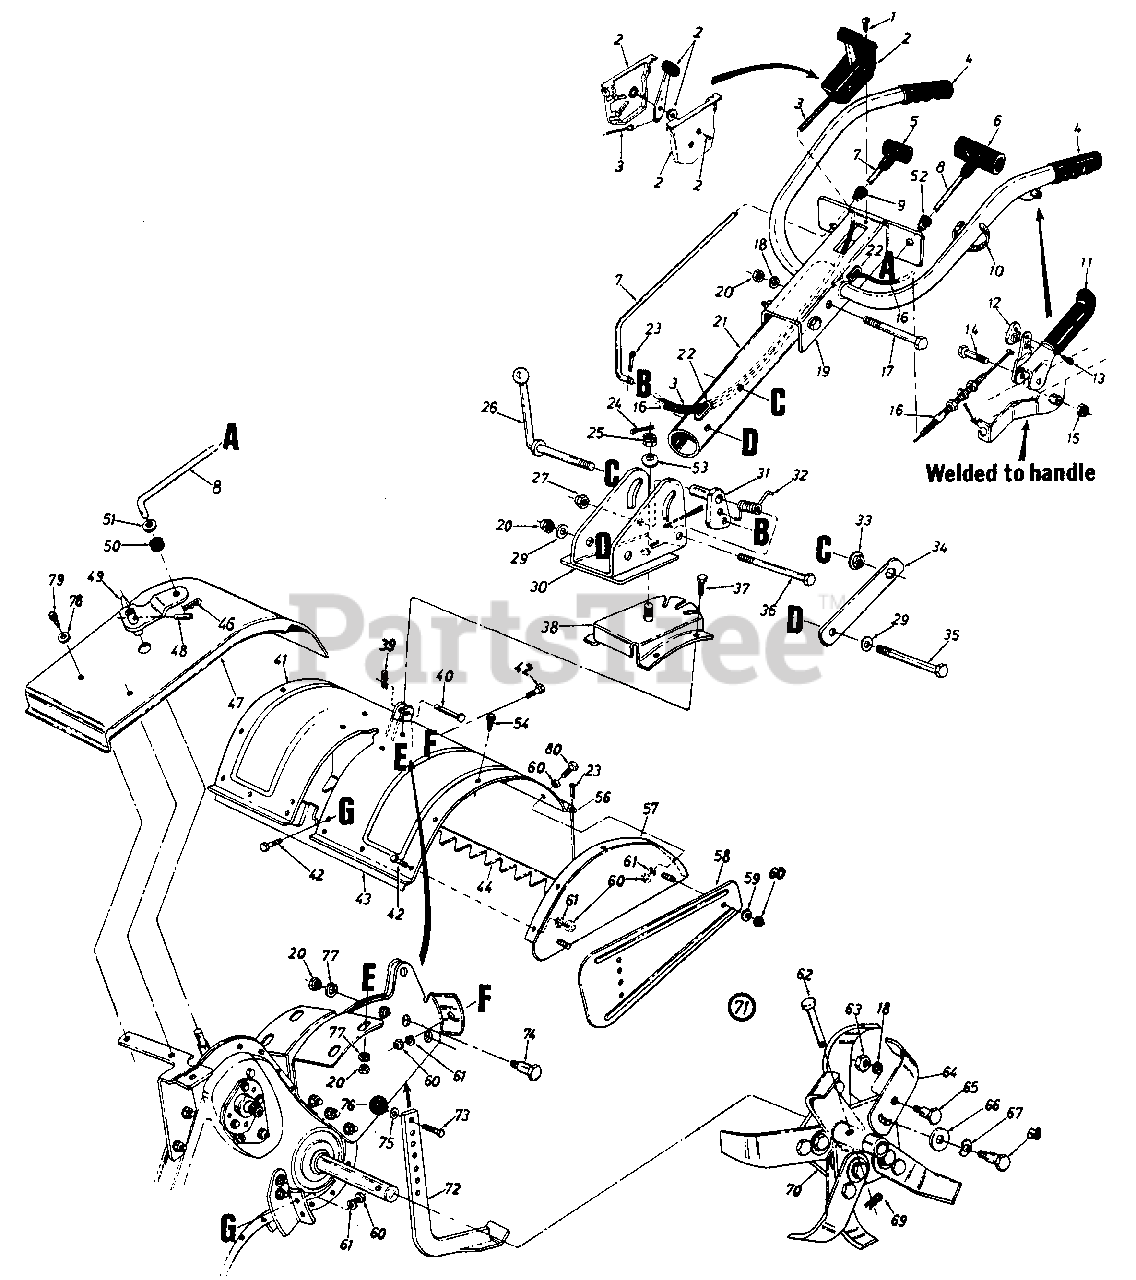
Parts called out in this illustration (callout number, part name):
1	SCREW-TRUSS TAP
2	CONTROL BOX-THROTTLE
3	CABLE-THROTTLE
4	GRIP-BLACK
7	ROD-CLUTCH
8	ROD-CONTROL
10	TIE-CABLE
12	HOLD DOWN-CABLE
13	SCREW-TAP
14	SCREW-HEX 3/8-16 X 2.00
15	NUT-HEX CENTER L-JAM
16	CABLE-CLUTCH CONTROL
17	SCREW-HEX 3/8-16 X 3.00
18	WASHER-HDL 3/8
19	HANDLE ASSY
20	NUT-HEX 3/8-16
23	PIN-COTTER-3/32 DIA X .75
24	PIN-COTTER 1/8 X 1 5/8
25	NUT-HEX SLOTTED
27	NUT-HEX CENTER L-3/8-16
29	WASHER-BELL .400 ID X .88 X .060
30	PIVOT BRKT ASSY
31	CRANK ASSY-POS
32	SPRING-HDL ADJ
33	NUT-HEX FLANGE
34	BRACKET-RETAINER
35	SCREW-HEX 3/8-16 X 3.25
36	SCREW-HEX 3/8-16 X 3.00
37	SCREW-HEX 3/8-16 X .75
40	PIN-CLEVIS 3/8 X 1.620
43	BRACKET-REINF
46	PIN-INTERN COT-5/16 DIA
49	CRANK ASSY-SHIFT
50	WASHER-RUBBER
51	WASHER-FL-.406 ID X 1.25 OD
53	WASHER-BELL
54	SCREW-TAP 5/16-18X.62
56	ROD-TILLER FLAP
60	NUT-HEX 5/16-18
61	WASHER-LOCK-5/16
62	PIN-CLEVIS 3/8 X 1.620
63	NUT-HEX 3/8-24
65	SCREW-SHLD 3/8-24 X 3/4 LG
66	WASHER-FL .51IDX1.50ODX.075
67	WASHER-BELL .515X1.4
68	SCREW-SHLD
69	PIN-COTTER
73	SCREW-HEX 3/8-16 X .75
74	SCREW-SHLD .500 DIA X .660
75	WASHER-FL-.385 ID X .62 OD X .033
76	KNOB-BALL 1-3/8 " DIA.
77	WASHER-LOCK-3/8
78	WASHER-FL
79	SCREW-HEX WASH SF TAPP
80	SCREW-HEX 5/16-18 X 1.25
